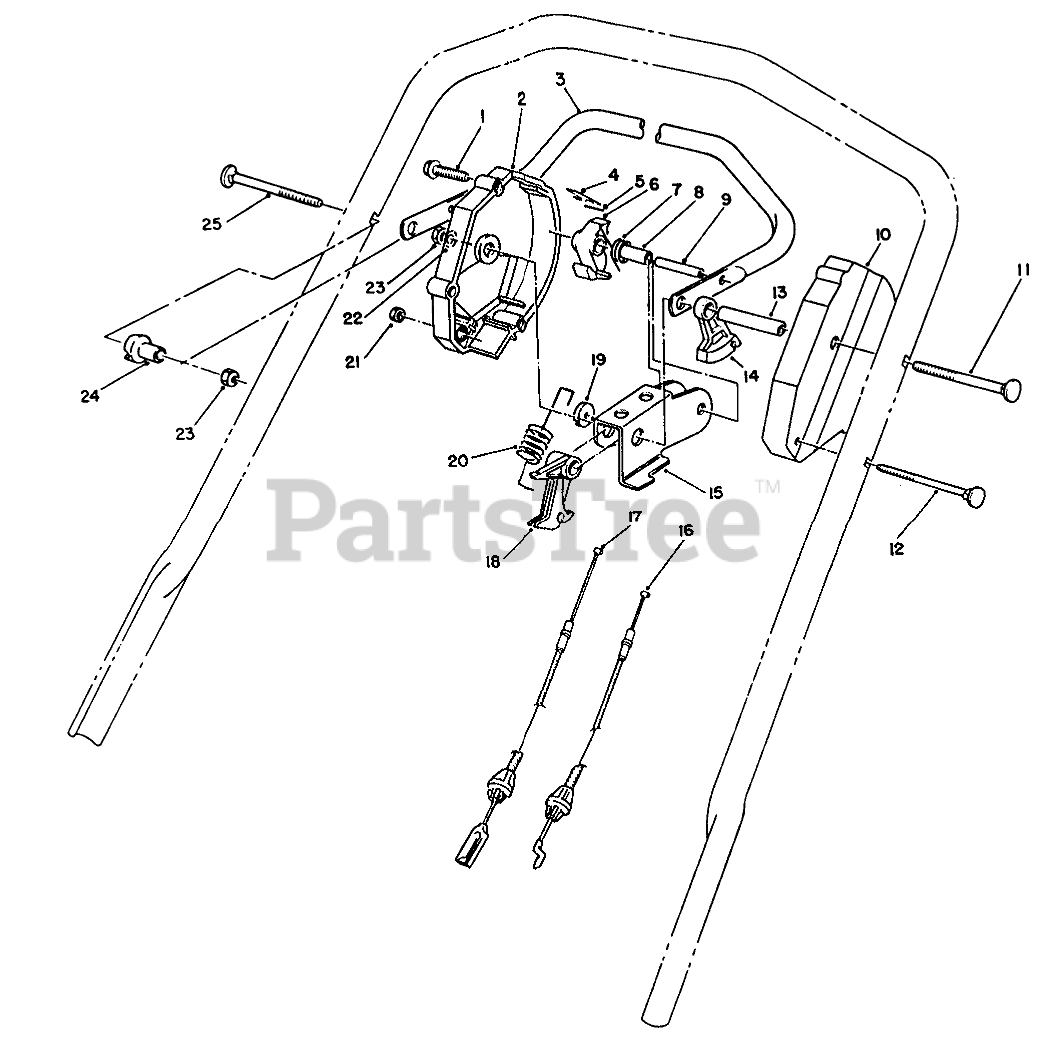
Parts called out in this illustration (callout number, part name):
1	SCREW-HWHTF
2	Housing-Control
3	Bar-Control
4	SPRING-LEAF
5	PIN-INSERT
6	HOOK-CONTROL
7	SPRING-TORSION
8	SPACER
9	PIN-ROLL, SLOTTED
10	HOUSING-CONTROL, LH
11	Screw-Handle
12	HANDLE SCREW
13	TUBING-SPACER
14	LEVER-TRACTION
15	ROCKER
16	TRACTION CABLE
17	BBC CABLE ASSEMBLY
18	LEVER-CABLE
19	WASHER-NYLON
20	SPRING-DETENT
21	NUT-HEX
22	WASHER-PLAIN
23	NUT-LOCK, NI
24	SPACER-SUPPORT
25	SCREW-HANDLE
